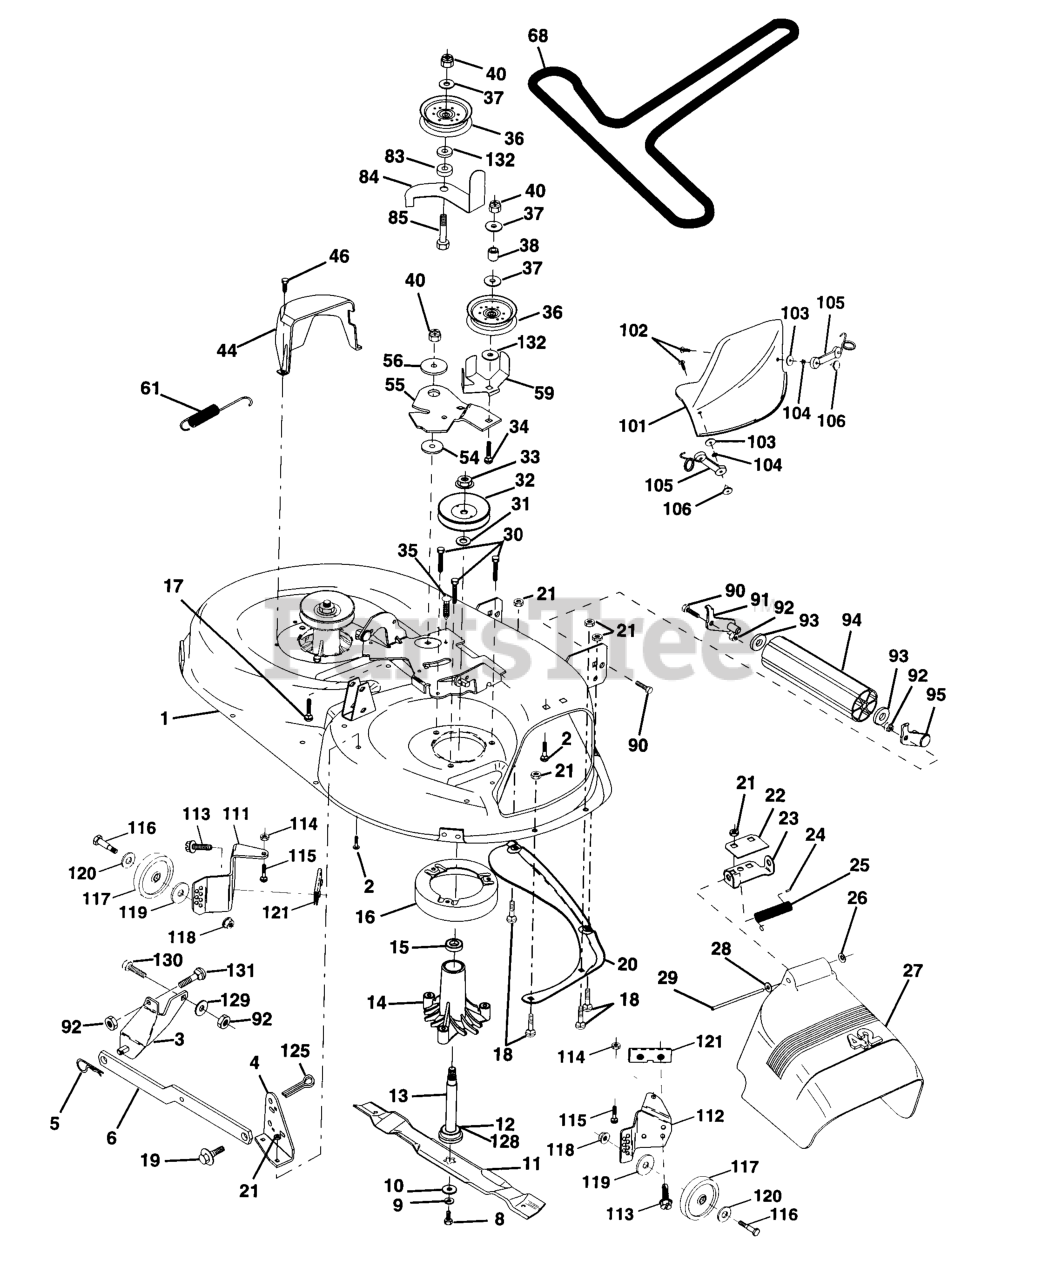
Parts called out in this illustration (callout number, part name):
1	DECK 42"
2	RP BOLT 5/16-18 X3/4 ZN/YEL GR
3	BRKT ASM SWAY BAR
4	BRKT DECK SW BAR
5	RETAINER-SPRNG RB
6	REAR SUSP ARM
8	BLADE BOLT
9	LOCKWASHER
10	WASHER.BLADE
11	BLADE.42".MULCH
12	BEARING.BALL.#6204.(MANDREL)
13	SHAFT ASM VENT
14	HOUSING.MANDREL.VENTED (MACHD)
16	STRIPPER
17	BOLT CARRIAGE
18	BOLT
19	BOLT SHD 5/16-18
20	BAFFLE
21	LOCKNUT
22	STIFFENER BRACKET
23	DEFLECTOR BRACKET
24	CAP-SLEEVE LT
25	SPRING TORSION
26	NUT PUSH M
27	SHIELD.DEFLECTOR.MOWER.42".BLK
28	Washer 11/32 X 5/8 X 16 Ga
29	ROD.HINGE
30	SCREW
31	WASHER
32	PULLEY/MANDREL
33	NUT
35	FASTENER.XMAS.TREE
36	FLAT IDLER PULLEY
37	WASHER
38	IDLER SPRING SPACER
44	GUARD MANDREL LH BLACK
46	SCREW.1/4-20X5/8
54	HARDENED WASHER
55	IDLER ARM
56	SPACER RETAINER
59	GUARD, BELT
61	SPRING EXTENSION
68	V-BELT TRIPATH
84	KEEPER.BELT.IDLER
85	BOLT
90	BOLT
91	BRACKET LH (A)
92	NUT
93	Washer 17/32 X 7/8 X 16 Ga
94	NOSE ROLLER
95	BRACKET RH (B)
101	COVER MULCH 42"
102	SCREW
104	LOCKWASHER #10
105	LATCH ASSEMBLY
106	WELDNUT
111	BRACKET WHEEL GAUGE LH 42" DK
112	BRACKET WHEEL GAUGE RH 42" DK
113	SCREW.THDROL.5/16-18X3/4.TTY
114	NUT
115	BOLT.CARR.5/16-18X1/2
116	BOLT M
117	WHEEL.GAUGE.BLK.4.93
118	LOCKNUT
119	WASHER.5/16.FLAT.STE.STD.
120	Washer 17/32 x 15/16 x 12 Ga.
121	BRACKET.EXTRUDED.GAGE.WHEEL
125	Cotter Pin
128	WASHER FELT
129	WASHER
130	BOLT
131	BOLT D
